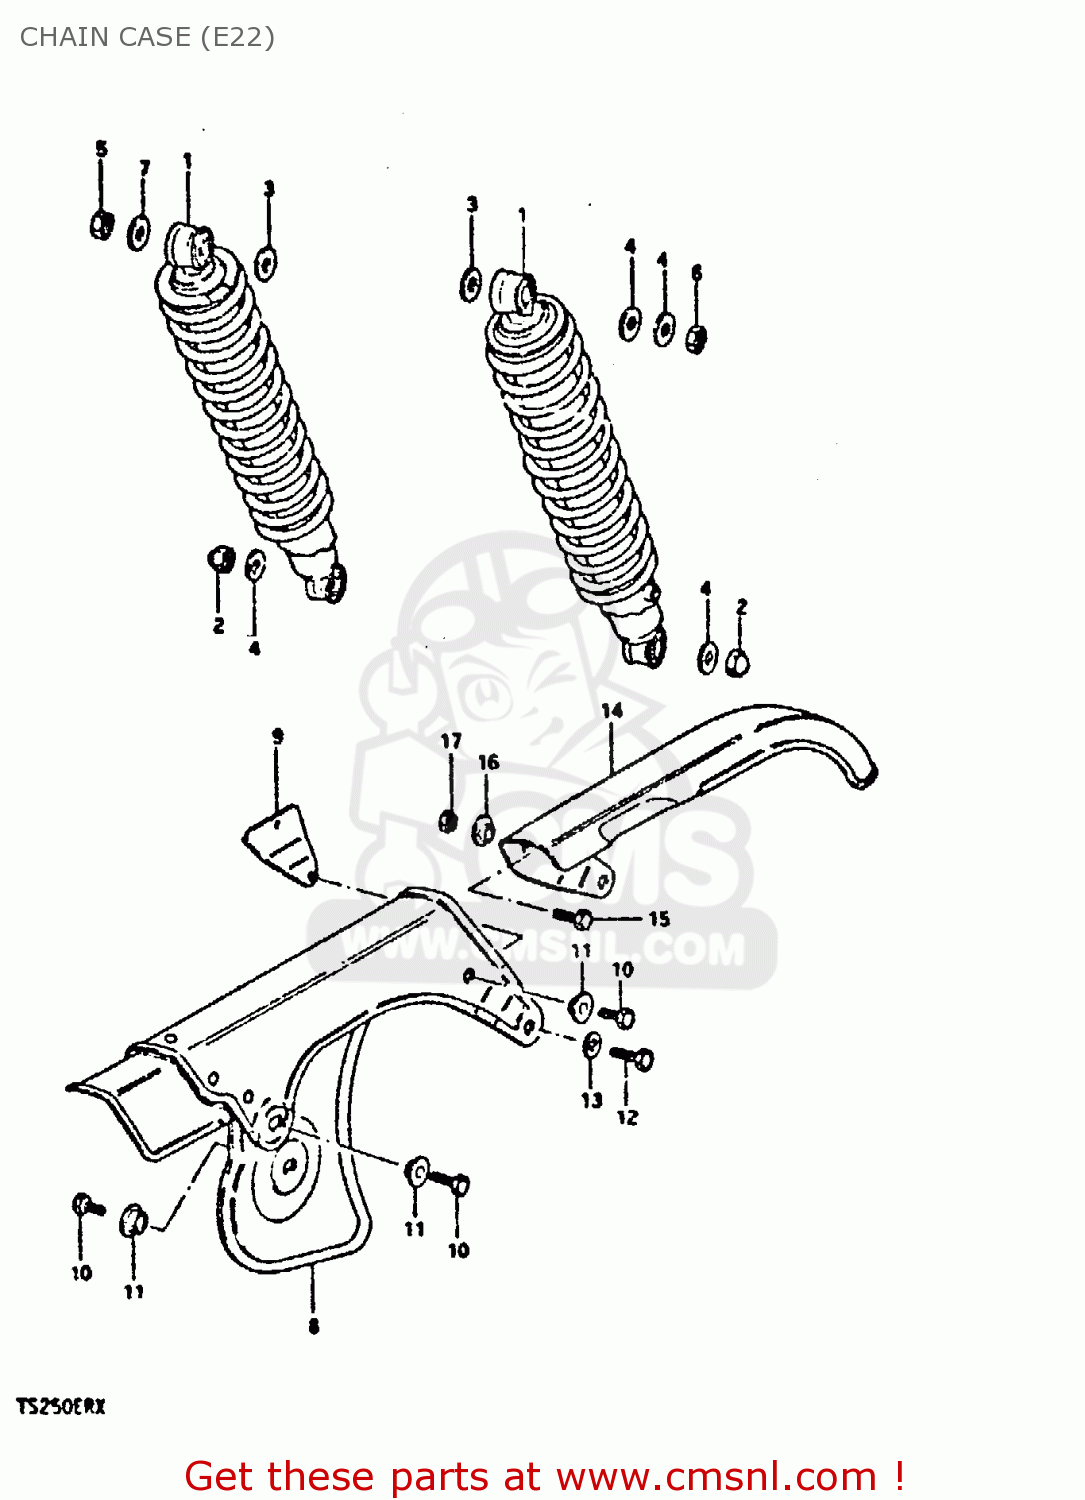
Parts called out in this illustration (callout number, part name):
1	ABSORBER ASSEMBLY,REAR SHOCK
2	NUT, LOWER LH
3	WASHER
4	WASHER
5	NUT
6	NUT
7	WASHER (12.5X24X3.2)
8	CHAIN CASE
9	REINFORCEMENT,CHAIN CASE
10	BOLT(6X8)
11	WASHER
12	BOLT
13	WASHER
14	CHAIN CASE, AND
15	BOLT
16	WASHER
17	NUT
